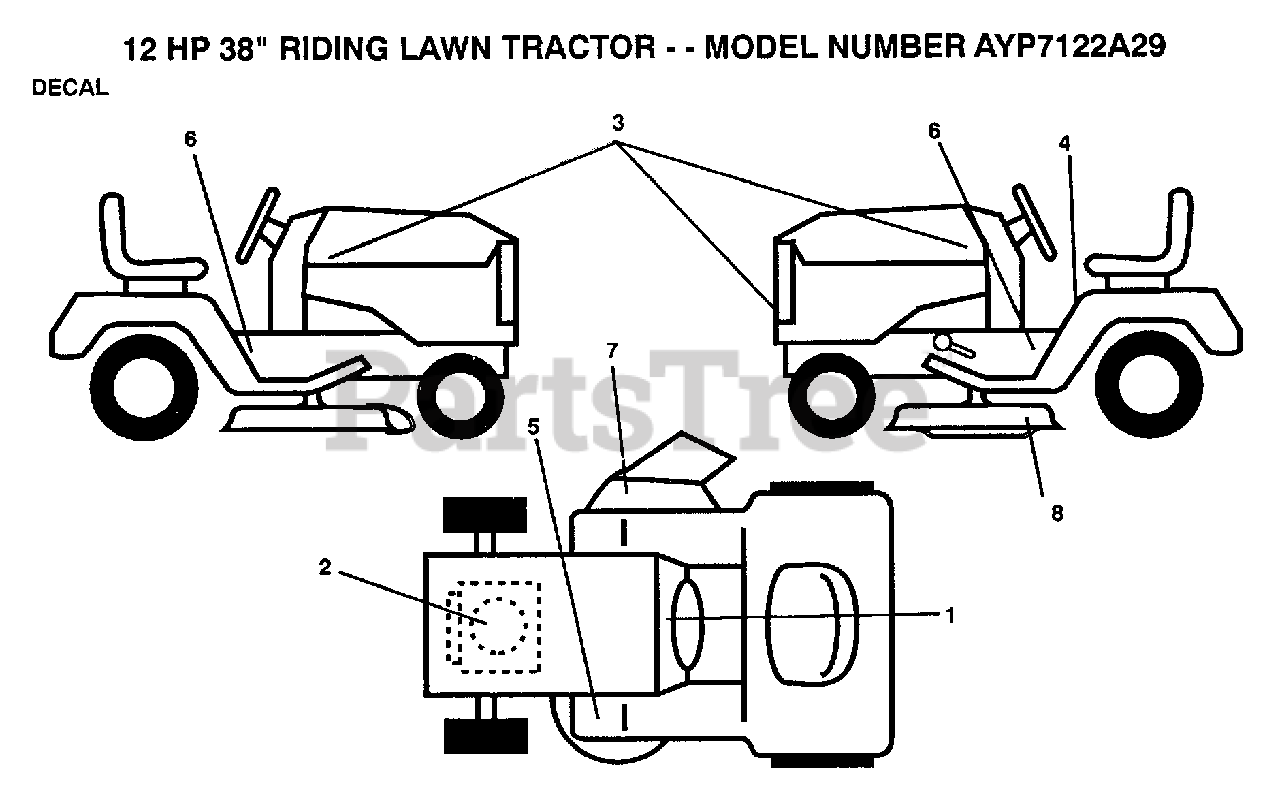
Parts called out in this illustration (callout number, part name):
2	DECAL.ENG.271967
7	DECAL WARING
8	DECAL INSTRUCTION CAUTION
